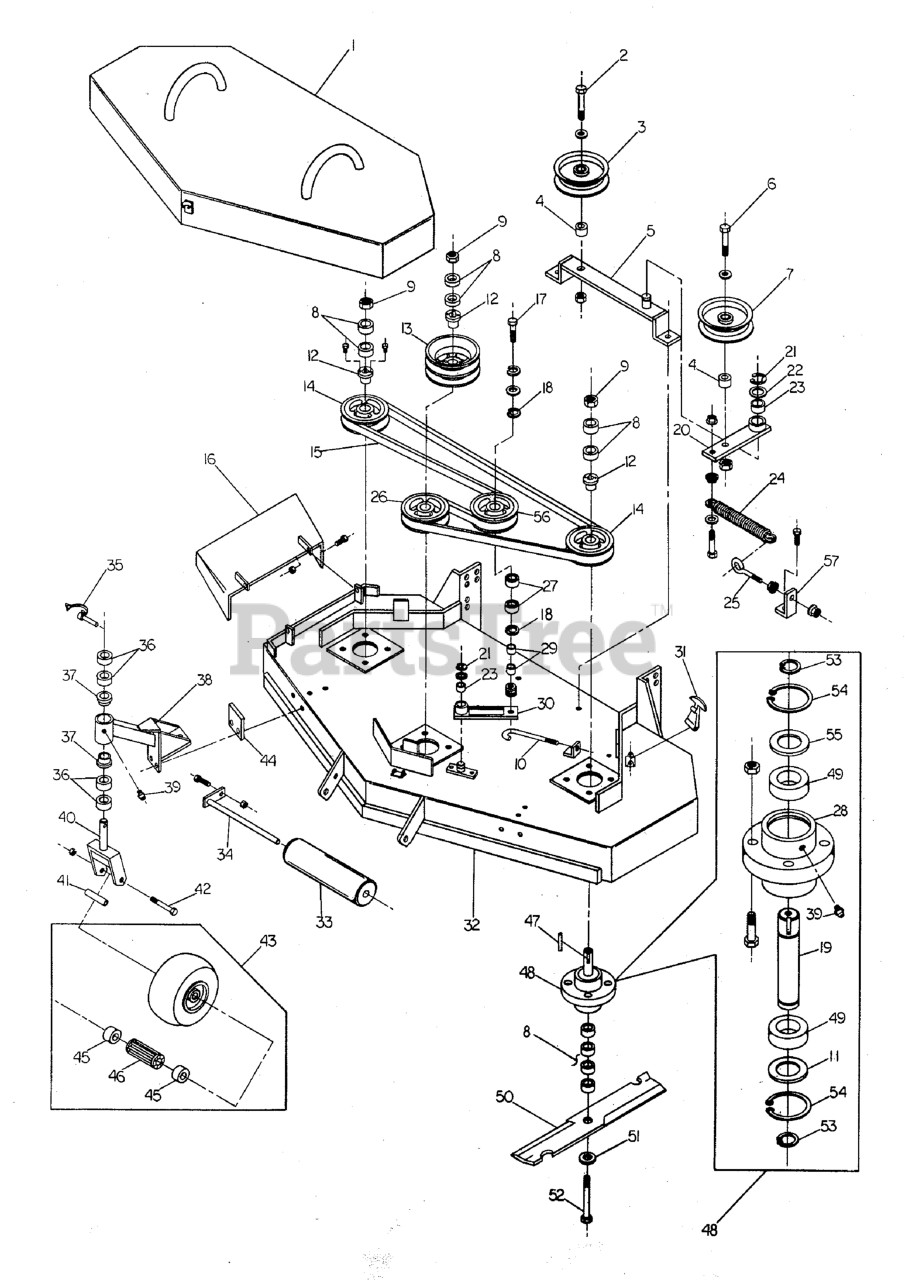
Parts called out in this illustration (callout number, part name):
1	61" DECK GUARD
1	48" DECK GUARD
2	1/2-13 x 3-1/2" Bolt
3	PULLEY, Backside Idler
4	SPACER, .50 x 1.00 X .69
5	Idler Mount
6	1/2-13 x 3" Bolt
7	PULLEY, V-Idler
8	SPACER, .63 x 1.06 x .23
9	NUT, 5/8-11 Hex
11	SPINDLE WASHER, Bottom
12	BUSHING, Tapered Hub
13	Double Pulley
14	PULLEY, Spindle
15	BELT, Blade Spindle
16	CHUTE, DISCHARGE WELDMENT
17	1/2-20 x 2-1/4" Bolt
18	SNAP RING, Internal
19	SPINDLE SHAFT
20	IDLER ARM, Complete
21	C-CLIP
22	SHIM
23	BUSHING, Brass
24	SPRING, Extension
25	EYEBOLT
26	SPINDLE PULLEY
27	BEARING, BALL 11/16X1-9/16X15/32
28	SPINDLE HOUSING
29	INSERT, Bearing
30	IDLER ARM
31	RUBBER LATCH
32	61" MOWER HOUSING (4 Bolt)
32	48" MOWER HOUSING
33	ROLLER
35	PIN, Lynch
36	SPACER, 1.02 x 1.56 x .50
37	BUSHING, Flange
38	Caster Support
39	GREASE FITTING
40	YOKE, Caster
41	AXLE, Caster Wheel
42	1/2-13 x 5-1/2" Bolt
43	Caster Assembly
44	Caster Mount Spacer
45	RETAINER, Bearing
46	BEARING, ROLLER 3/4" ID X 3.25" (ONE PER TIRE)(SV)
47	KEY, 1/4 SQ. X 2-1/2
48	SPINDLE ASSEMBLY, Complete
49	BEARING
50	MOWER BLADE, 21"
50	MOWER BLADE, 16-1/4"
51	5/8 Washer
52	BOLT, 5/8-11 x 9-1/2
53	SNAP RING, External
54	SNAP RING, Internal
55	SPINDLE WASHER, Top
56	PULLEY, Idler
57	SPRING ANCHOR
57	Spring Anchor
